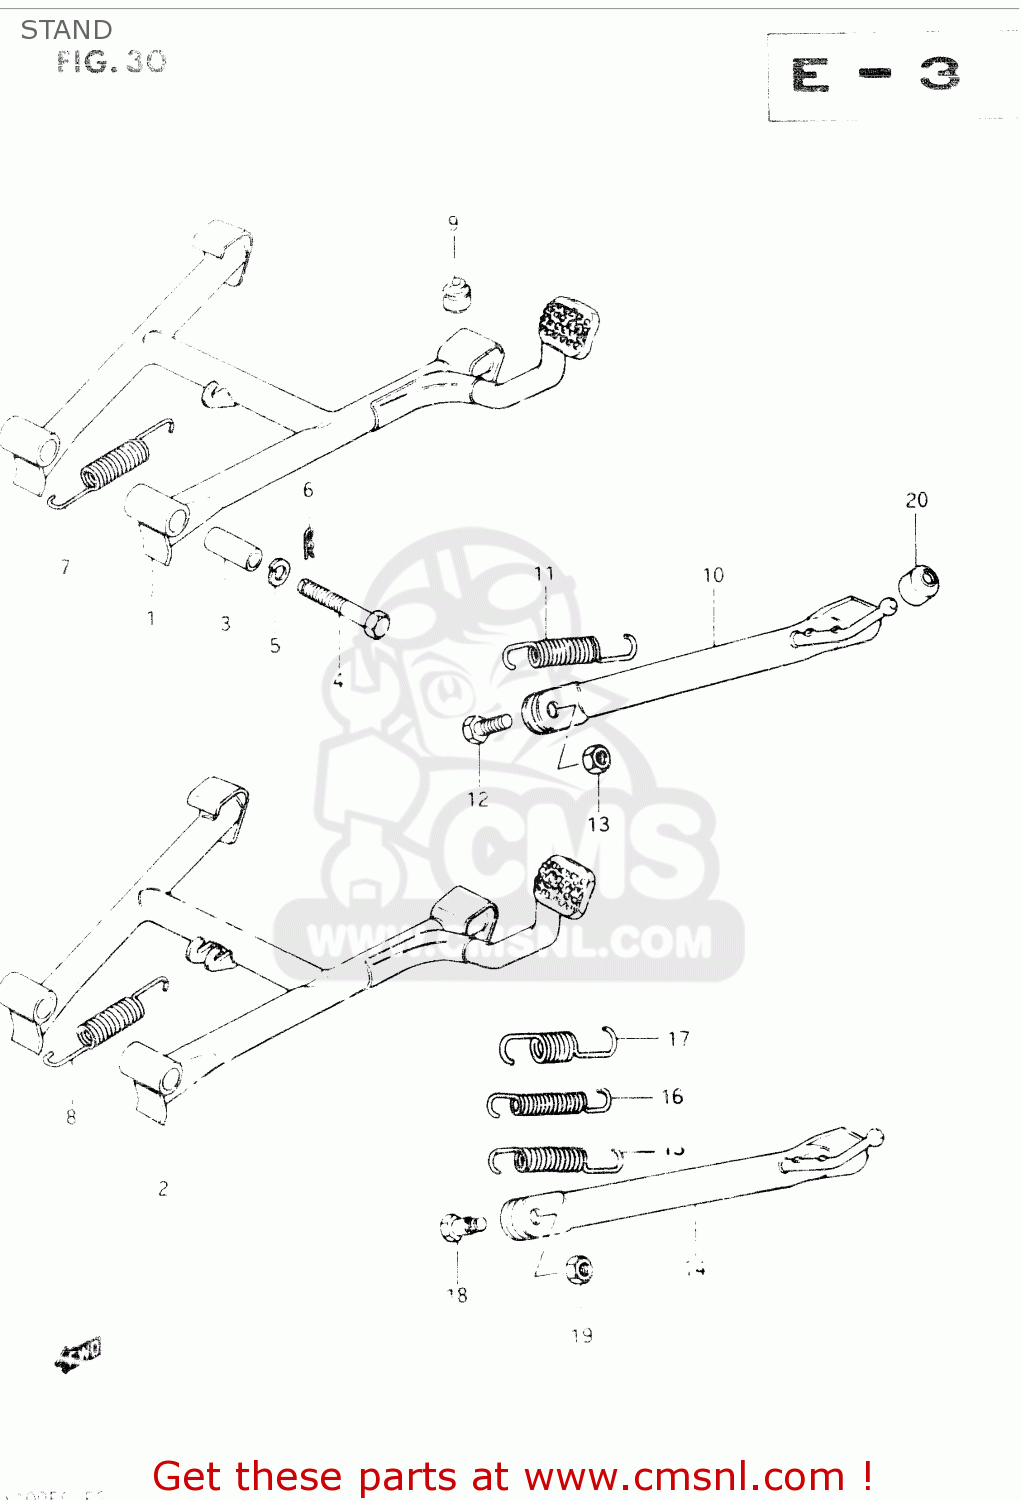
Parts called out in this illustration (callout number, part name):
1	STAND,CENTER
2	STAND, CENTER
3	SPACER(10X16X38.8)
4	BOLT
5	LOCK WASHER
6	CLIP
7	SPRING
8	SPRING
9	CUSHION
10	STAND,SIDE
11	SPRING
12	BOLT(10X30)
13	NUTM10X1.25X8
14	STAND, PROP
15	SPRING
16	SPRING
17	SPRING, OUTER
18	BOLT L:30
19	NUTM10X1.25X8
20	CUSHION
